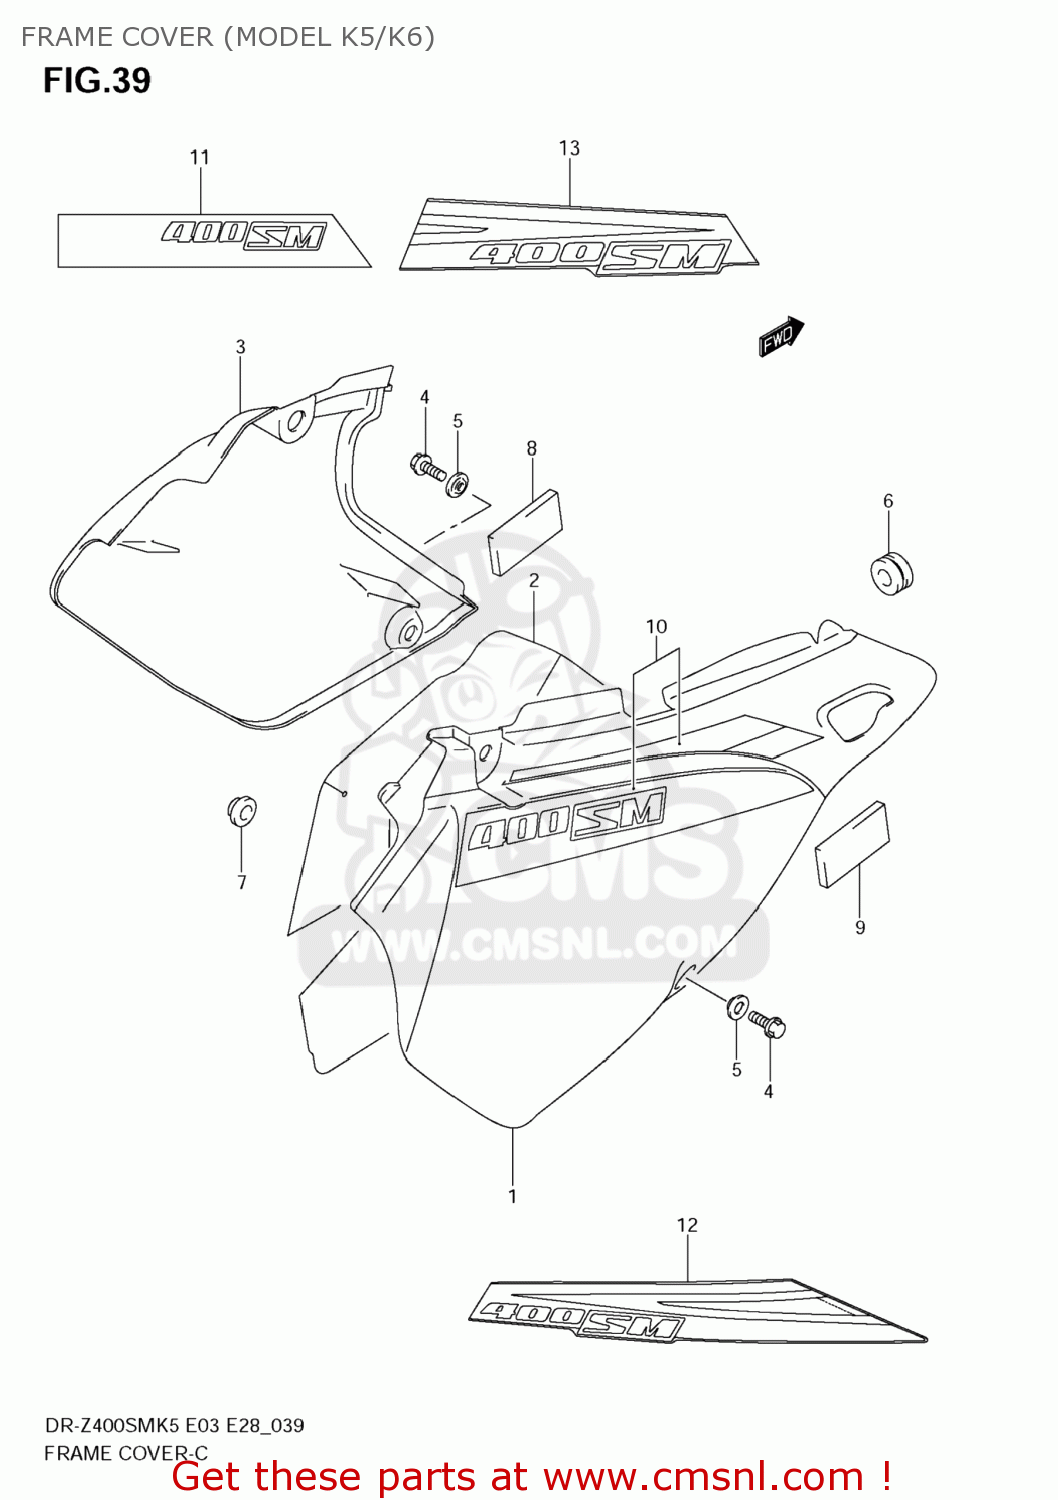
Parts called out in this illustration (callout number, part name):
1	COVER,FRAME,RIGHT (BLACK)
2	SHIELD,FRAME COVER,R
3	COVER,FRAME,LEFT
4	BOLT(6X12)
5	WASHER
6	CUSHION
7	CUSHION
8	CUSHION,FRAME COVER,L
9	CUSHION
10	TAPE SET,FRAME COVER,R
11	TAPE SET,FRAME COVER,L
12	TAPE,FRAME COVER,R
13	TAPE,FRAME COVER,L
